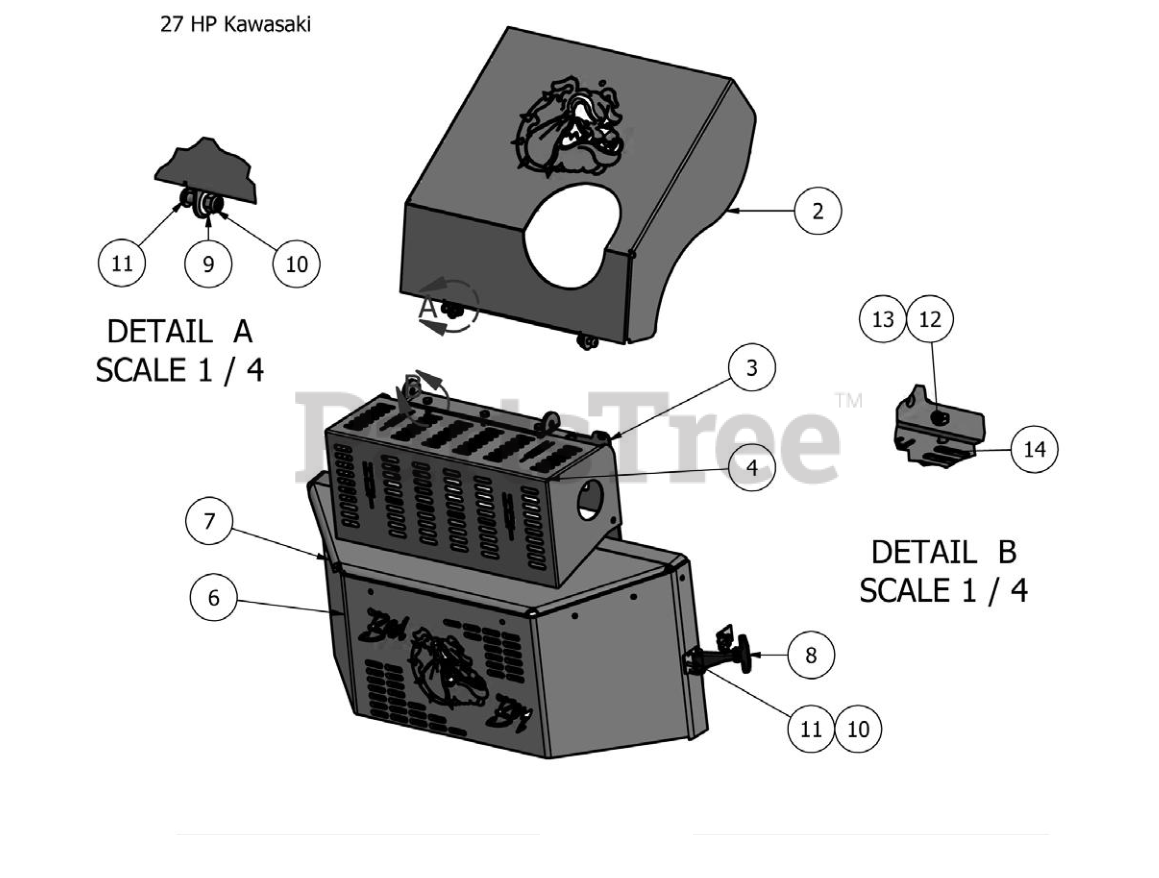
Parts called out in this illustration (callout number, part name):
1	AOS Pump Plate
2	Donaldson hood
3	Hood Holder Bracket
4	Muffler Guard
6	Back Pump Cover
7	Top Pump Cover
8	Pump Cover Latch
9	.360 ID Plastic Washer
10	1024 Nylock Nut
11	1024 x 1/2" Buttonhead Bolt
12	1/4" x 3/4" SS Buttonhead
13	1/4" Lock Washer
14	1/4" Hex Nut
